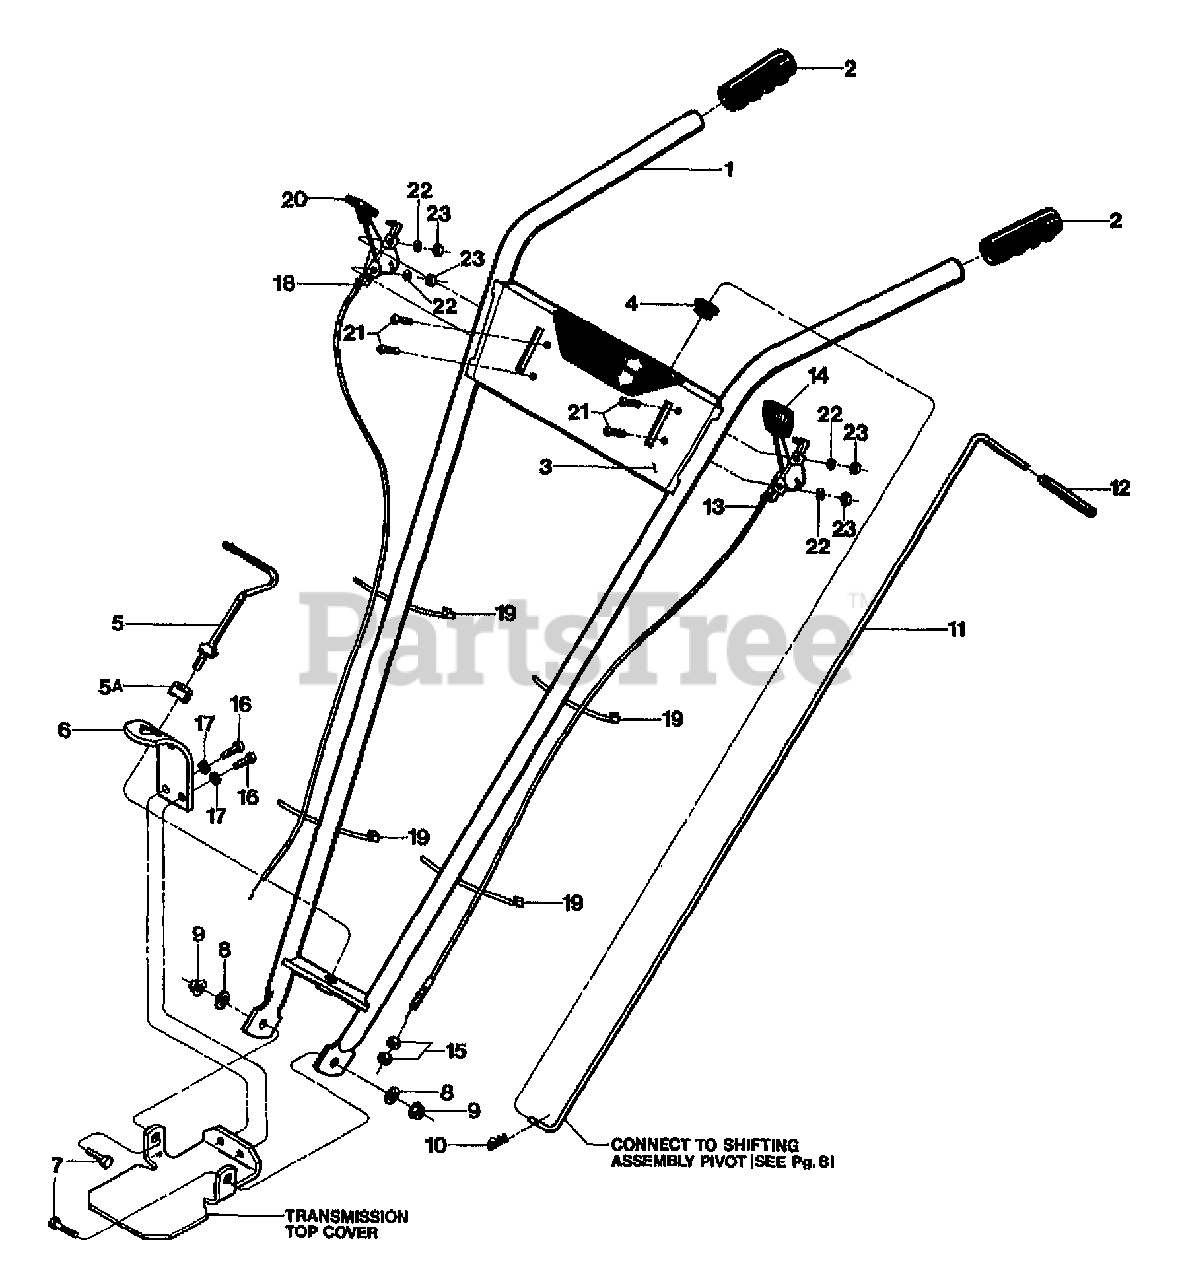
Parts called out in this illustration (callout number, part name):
1	ASSM-HANDLEBAR (INCL. 2-5A)
2	GRIP-H/BAR SMOOTH
3	DECAL-CONTROL PANEL ECONO
4	GROMMET-PLASTIC
5	ASSM-STUD H/B
5A	WASHER-1.0X.38X.375
6	PLATE-HANDLEBAR ADJUST
7	SCR-HH 3/8-16X1.0 G5 ZP
8	WASHER-FLAT 3/8 SAE
9	NUT-LOCK 3/8-16 NYLON ZP
10	PIN-CLIP .08
11	ASSM-DR CONTROL ROD - COMPLETE (INCL.GRIP, #9198)
12	GRIP-CONTROL ROD
13	KIT-WHL DRIVE CABLE (INCL. 14,15,19,21-23)
14	KNOB-WHEEL DRIVE CABLE
15	NUT-HEX 5/16-24
16	SCR-HH 3/8-16X.75 G5 ZP
17	WASHER-LK .375 @ DEPL
18	CABLE-THROTTLE PONY OPC
19	TIE-RED (PLASTIC)
20	KNOB-THROTTLE CABLE
21	SCR-RH M10-32X.5 MACH
22	WASHER-LK M10
23	NUT-HH M10-32X.125
